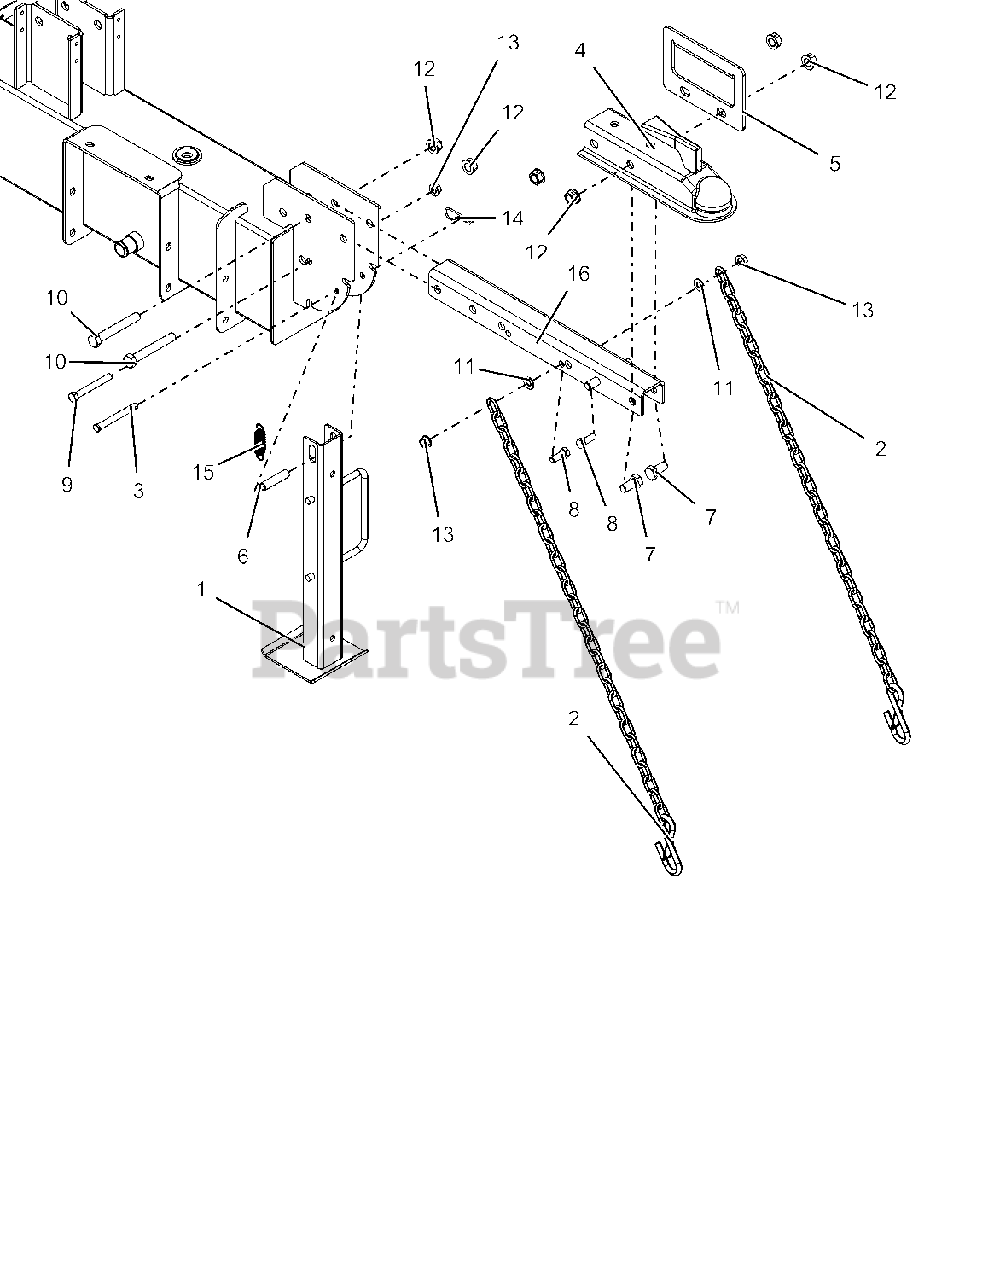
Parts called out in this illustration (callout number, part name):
1	WLDMT, JACK STAND
2	CHAIN, SAFETY 3/16"-30LINK
3	PIN-CLEV .371X3.25 YWZC
4	HITCH, BALL-2"
5	HANDLE, SPLITTER DRAW BAR
6	SPCR, WHEEL .385X.500X2.00
7	@BLT-HEX .50-13X1.00 GR5 YWZC
8	@BLT-HEX .38-16X1.00 GR5 YWZC
9	@BLT-HEX .38-16X3.00 GR5 YWZC
10	@BLT-HEX .50-13X3.50 GR5 YWZC
11	@WSHR-FL-STL.406X.812X.065 YWZ
12	NUT-LK-CTR-FLG .50-13 YWZC
13	@NUT-LK-TOP-FLG .38-16 YWZC
14	HAIRPIN, #7 CLIP .094X2.31 YWZ
15	SPRG, TENSION .063X.625X2.50
16	HITCH BAR W/DECALS
